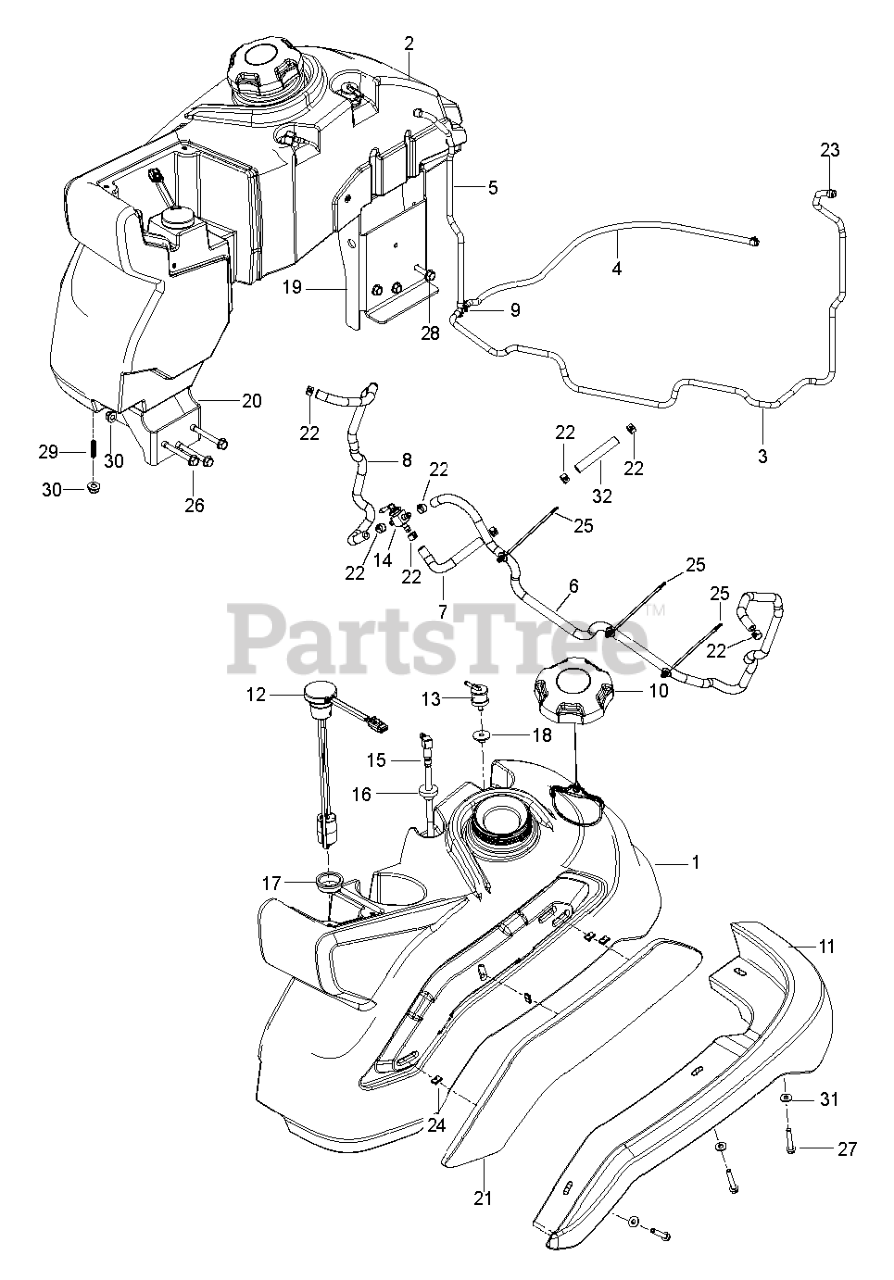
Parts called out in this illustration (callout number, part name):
1	FUEL.TANK.ASM.LH.PZ.REFRESH.18
1	TANK UNIT ASSY LH 2018 PROD. Y
2	TANK UNIT ASSY RH 2018 PROD. Y
2	FUEL.TANK.ASM.RH.PZ.REFRESH.18
3	HOSE 3/16" VAPOR LINE 41" LENG
4	HOSE 3/16" VAPOR LINE 7" LENGT
4	HOSE.3/16".VAPOR.LINE.17"LGTH
5	HOSE.3/16".VAPOR.LINE.17"LGTH
6	HOSE 1/4" LOW PERMEATION FUEL
7	HOSE.1/4".LOW.PERM.FUEL.LN.8"
8	HOSE.1/4".LOW.PERM.FUEL.LN.24"
9	TEE, FUEL LINE 3/16"
10	CAP, FUEL
11	GUARD.MUD.LH
12	SENSOR.FUEL.LVL.FLOAT.V500
13	VALVE.FUEL.CHECK
14	FUEL VALVE
15	TUBE.ASM.FUEL.TANK.PICK-UP.LH
16	BUSHING OUTLET T
17	GROMMET, FUEL SENSOR
18	GROMMET.CHECK.FUEL
19	BRACKET.FUEL.TANK.REAR.SUP.431
20	BRACKET.FUEL.TANK.REAR.SUP.431
21	COVER.LH.FUEL.TANK/CONSOLE APP
22	HOSE CLAMP
23	CLAMP, HOSE
24	CLIP.U-TYPE
25	CABLE.TIE.6".FIRTREE.PZ.REFRES
26	BOLT HEX FLGHD 5/16-18X3 GR. 5
27	SCREW.1/4-20X1.5IN.HEX.MACH
28	SCREW
29	SCREW.5/16-18X1.25"THREADED
30	5/16-18 NYLOC FLANGE NUT
31	WASHER
32	HOSE.1/4".LOW.PERM.FUEL.LN.3"
